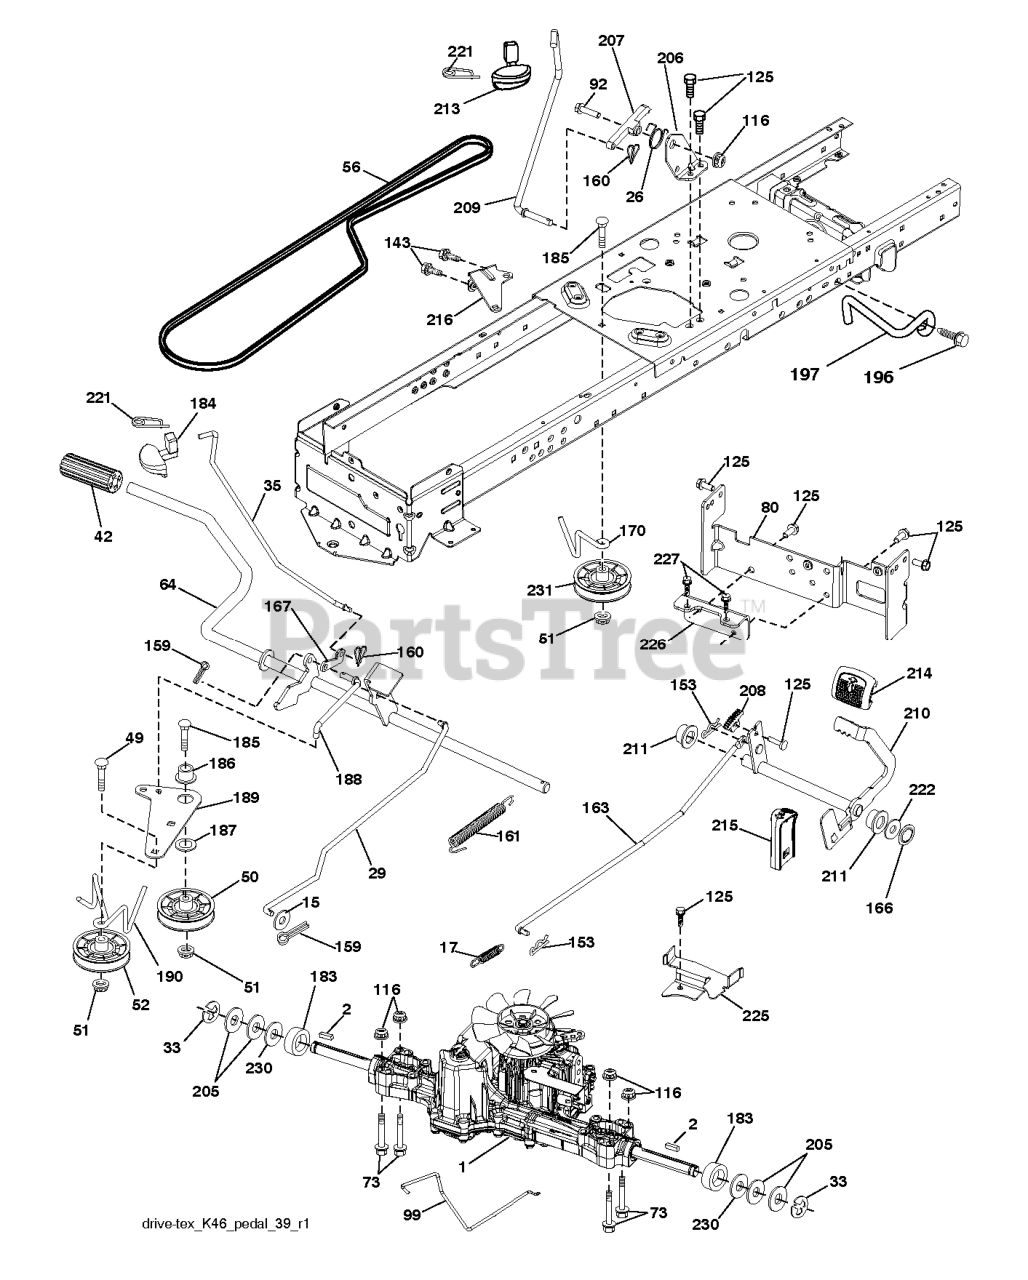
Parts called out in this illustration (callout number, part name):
2	SQUARE KEY
15	WASHER
17	SPRING.BRAKE.K46.GREEN
26	SPRING.RETURN.CRUISE
29	ROD.BRAKE.K46
35	ROD.BRAKE.PARKING.GT.H
42	PEDAL COVER T
50	IDLER.FLAT.910.OFFSET
51	NUT LOCK FLG 3/8-16 UNC
52	IDLER.V-GROOVE.910.OFFSET
56	V-BELT.MOWER.92.40.42/K46
64	SHAFT.ASM.PEDAL.BRK.CNTR
73	BOLT HEX 5/16-18 GR 5
80	STRAP TORQUE
92	BOLT
99	ROD.SPRING.BYPASS.K46.LT.Z
116	NUT LOCK HEX FLANGE 5/16-18
125	SCREW
143	Screw 5/16-18 x 1/2 Hex, Self Tapping 5/16-18 x 1/2
153	RETAINER M
159	COTTER PIN
160	RETAINER CLIP
161	SPRING, RETURN LT
163	ROD.CONTROL.PEDAL.K46
166	NUT.PUSH.625
167	LATCH.BRAKE.SPRING
170	KEEPER.CENTER SPAN.1.688
183	SPACER AXLE
184	HANDLE.PARKG.BRK.HUSQ X667
186	SPACER.RETAINER
187	WASHER 12/32X2X10GA
188	RP.LINK.CLUTCH.GROUND.DRIVE
189	BELLCRANK.GROUND.DRIVE.TEX.
190	KEEPER.BELLCRANK.DRIVE
196	SCREW 3/8-16X1
197	LINK.CLUTCH.ANIT-ROTAT
206	BRKT.MOUNT.LATCH.CRUIS
207	LATCH.CONTROL.CRUISE
208	GEAR.SECTOR.CONTROL.CR
209	ROD.CONTROL.CRUISE.GT.
210	ROCKER.ASM.PEDAL.CONTR
211	BEARING.NYLON
213	KNOB.CONTROL.CRUSIE.HU
214	PEDAL.FORWARD.PAD.TEX
215	PEDAL.REVERSE.TEX.GT.4
216	BRACKET.PULLEY.IDLER.W/TEX
221	RETAINER.SPRING.CLIP.H
222	WASHER 21/32 X 1-1/4 X 10 GA.
225	KEEPER.BELT.TRANSAXLE.K46
226	BRACKET.MOUNT.TORQUE.K46.TLT
227	SCREW.THDROL.5/16-18X3/4.TTY
230	WASHER.HARDENED
231	IDLER.V-GROOVE.1.688.OFFSET
